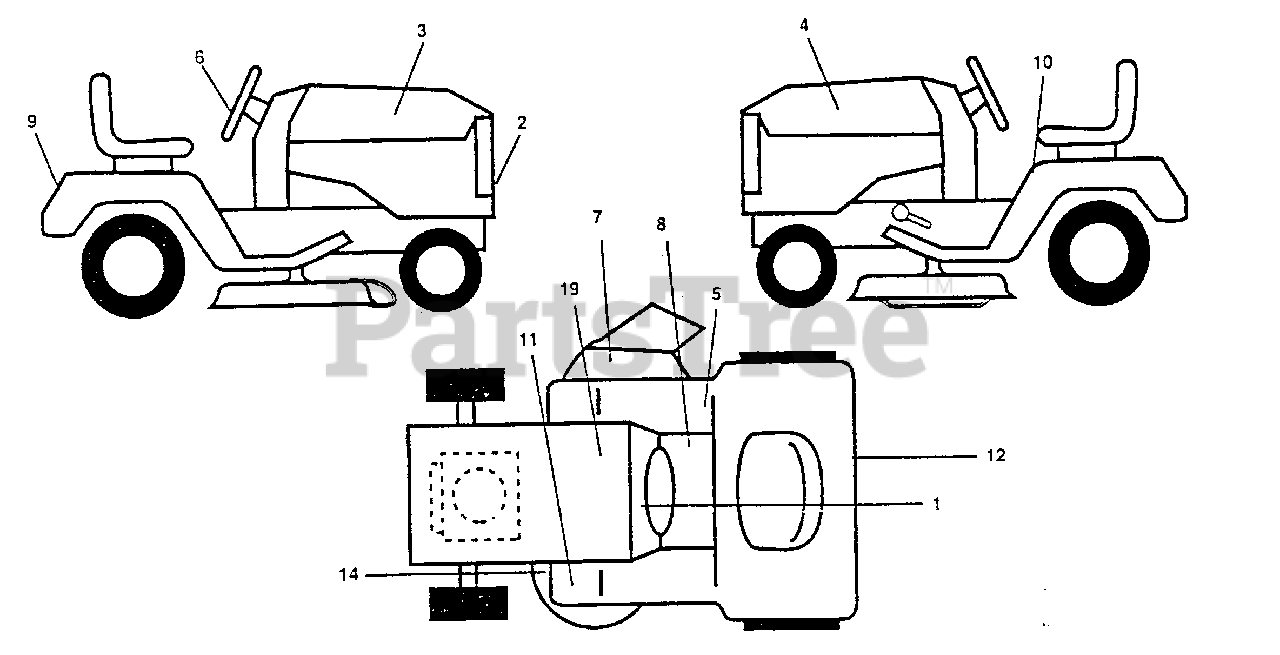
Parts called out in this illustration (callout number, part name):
1	Decal, Operating Instruction (AYP part number)
2	Decal, Grille
3	Decal, Hood, RH
4	Decal, Hood, LH
5	Decal, Insert Strg Whl (AYP part number)
6	Decal, Scl Cold Start Hyd
7	Decal, Warning Multi-Language (AYP part number)
8	Decal, Brake Parking Saddle (AYP part number)
9	Decal, Fender (AYP part number)
10	Decal, Caution (AYP part number)
11	Decal, Clutch/Brake (AYP part number)
12	Decal, D-Bar Ctrl. Mvt Hyd YT/GT (AYP part number)
14	Decal, V-Belt Schematic (AYP part number)
19	Decal, Battery (AYP part number)
